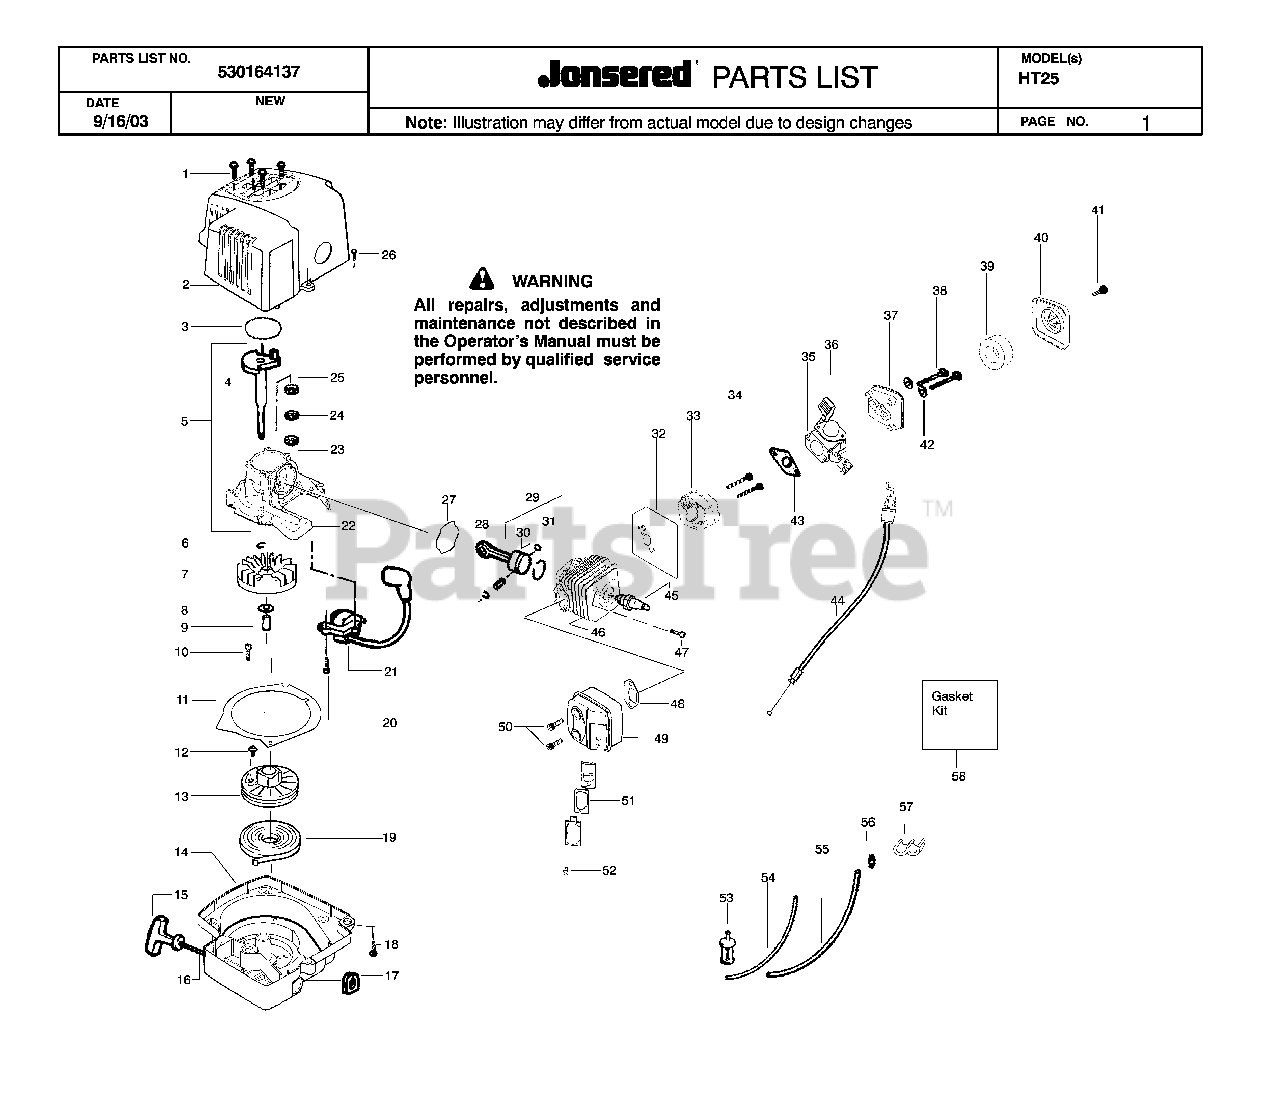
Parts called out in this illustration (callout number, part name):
2	ASSY-SHROUD
3	GASKET KIT
4	CRANKSHAFT
5	CRANKCASE
6	RETAINING RING
7	FLYWHEEL
8	WASHER FLAT
10	SCREW-10-16 X 1/2 HI-LO
11	PLATE-BAFFLE
12	SCREW SEMS TOOTHED WASHER
13	STARTER PULLEY
14	FAN HOUSING
15	HANDLE-STARTER
19	STARTER SPRING
21	IGNITION MODULE
22	CRANKCASE
23	OUTER BEARING
25	BEARING
27	GASKET KIT
29	PISTON
30	WRIST PIN RET.
31	PISTON RING
32	GASKET KIT
40	AIR FILTER COVER
42	WASHER
43	GASKET KIT
44	THROTTLE WIRE
45	PLUG-SPARK (RCJ-6Y)
48	GASKET KIT
50	SCREW MUFFLER
51	PARTITION
52	SCREW-6-19X5/16PLAST PA
53	ASSY-FUEL PICK-UP
56	FUEL LINE FITTING
58	GASKET KIT
